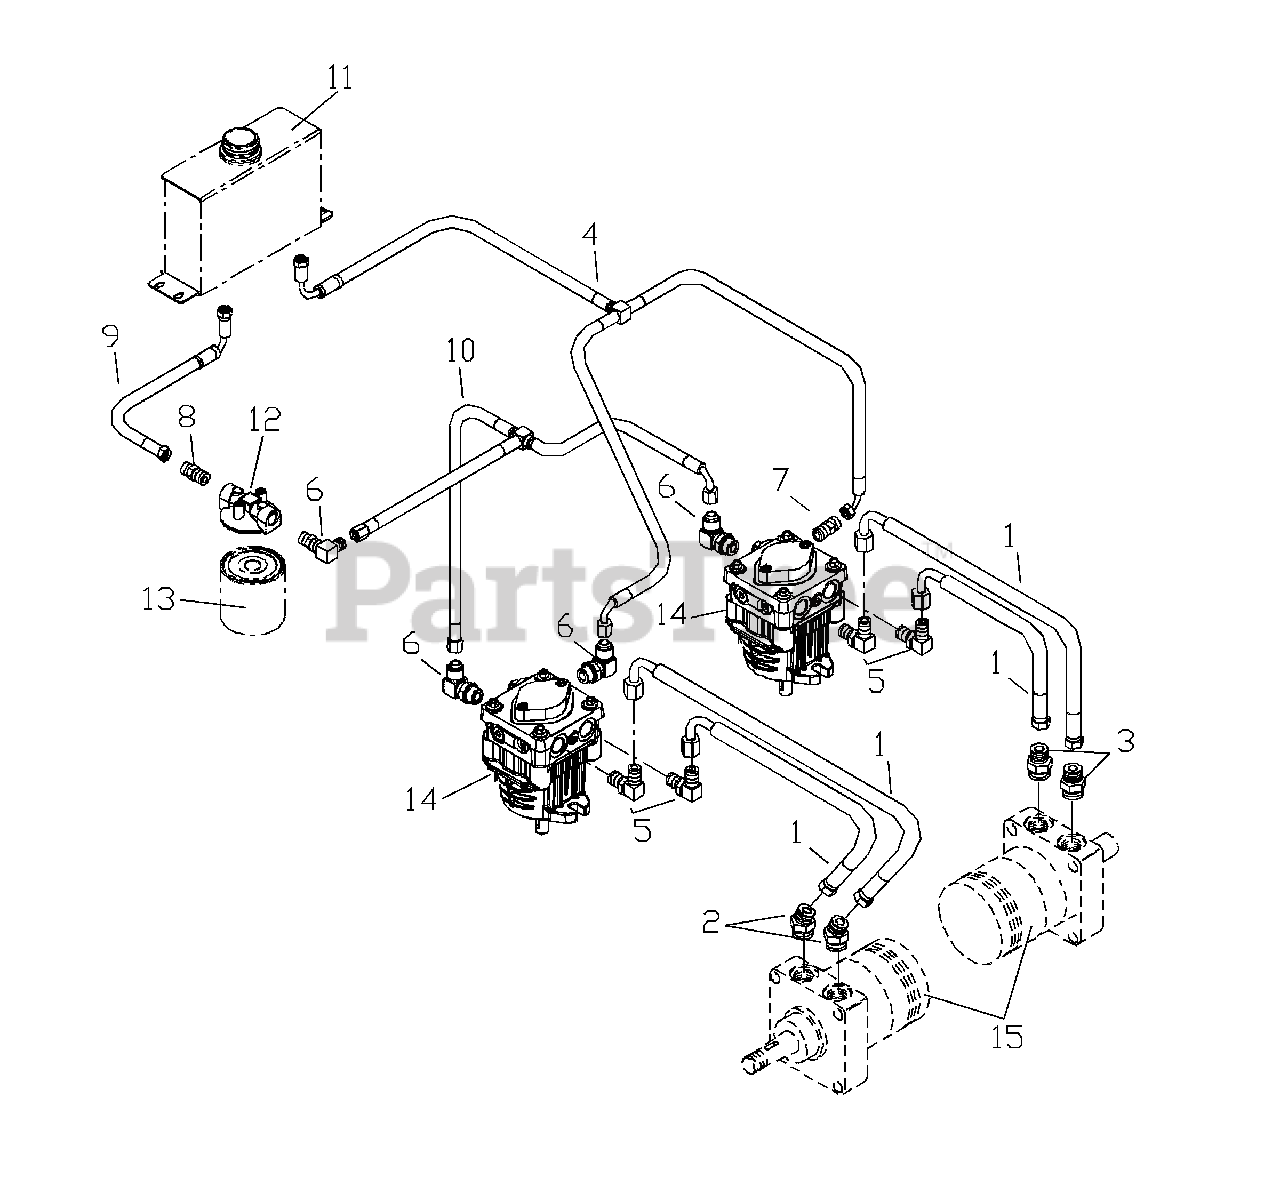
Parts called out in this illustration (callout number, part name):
1	HOSE
2	45 DEGREE ELBOW
3	STRAIGHT CONNECTOR
5	90 DEGREE ELBOW
6	90 DEGREE ELBOW
8	STRAIGHT CONNECTOR
9	HOSE
12	FILTER HEAD
14	PUMP
15	HYD. MOTOR
